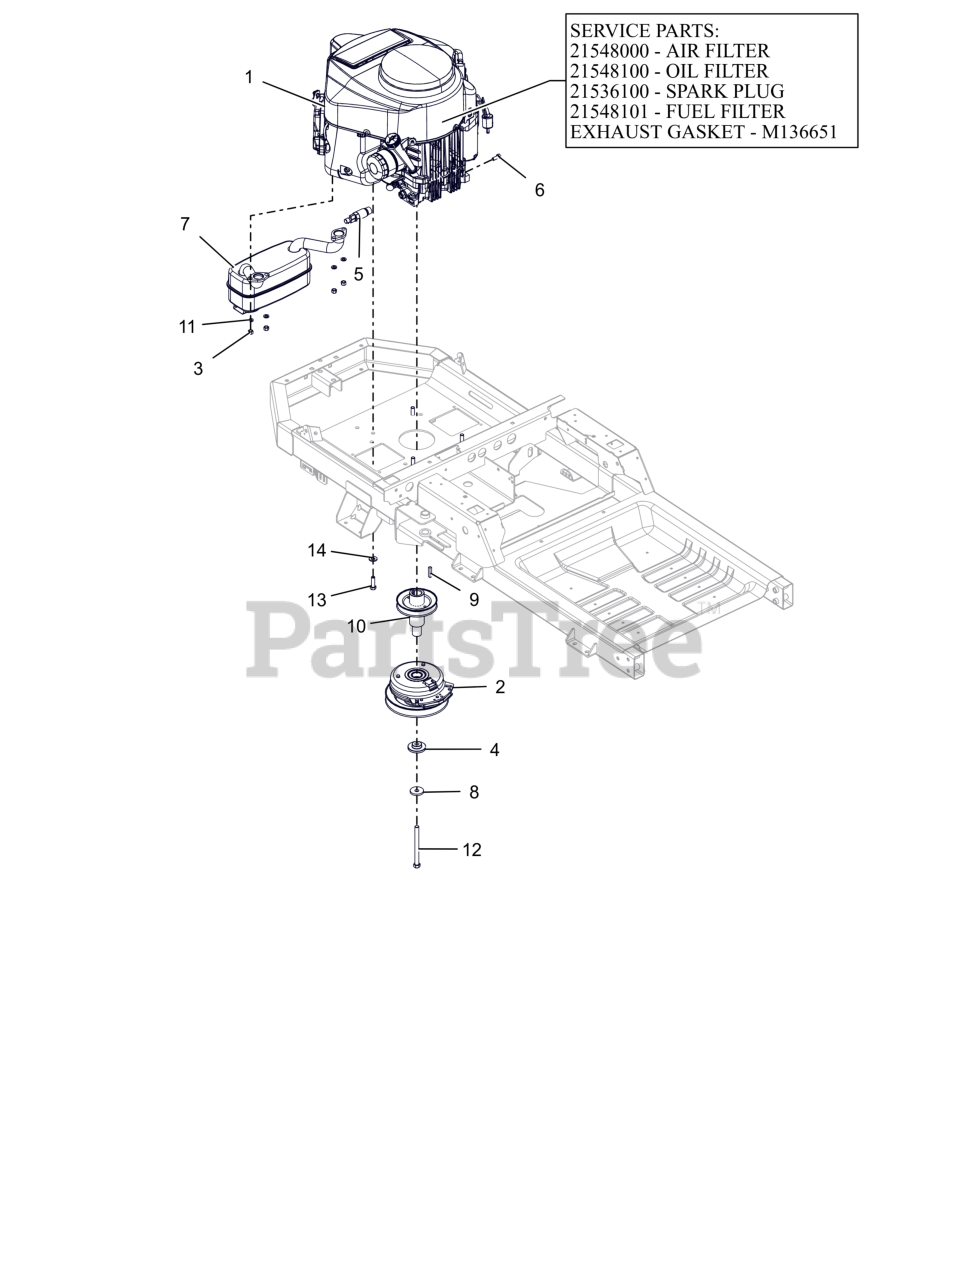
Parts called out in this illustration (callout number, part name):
1	ENGINE, KAWASAKI FR691 23HP
1	AIR FILTER, KAWASAKI FR
1	OIL FILTER, KAWASAKI FR
1	PLUG, SPARK
1	FUEL FILTER-KAWASAKI FR
1	GASKET, MUFFLER #
2	CLUTCH,105FTLB MONOPOLE 6.83"
3	NUT, HEX M8-1.25 G8.8 ZCC
4	BSHG-FLG .469X1.06X.574X2.0
5	DRAIN, OIL M20X2.5
6	BLT, HEX M8-1.25X20 G8.8 ZCC
7	MUFFLER - KAWASAKI
8	WASHER, 7/16" SPRING DISK
9	KEY-SQ .25 X 1.25 X .25 SAE
10	WLDMT, DRIVE SHEAVE (LONG)
11	WSHR,LK-REG .312X.078 ZCC
12	BLT, HEX .44-20X5.00 G8 ZCC NT
13	BLT, HEX .38-16X1.25 G5 ZCC NT
14	WASHER, 3/8" SPRING DISC
